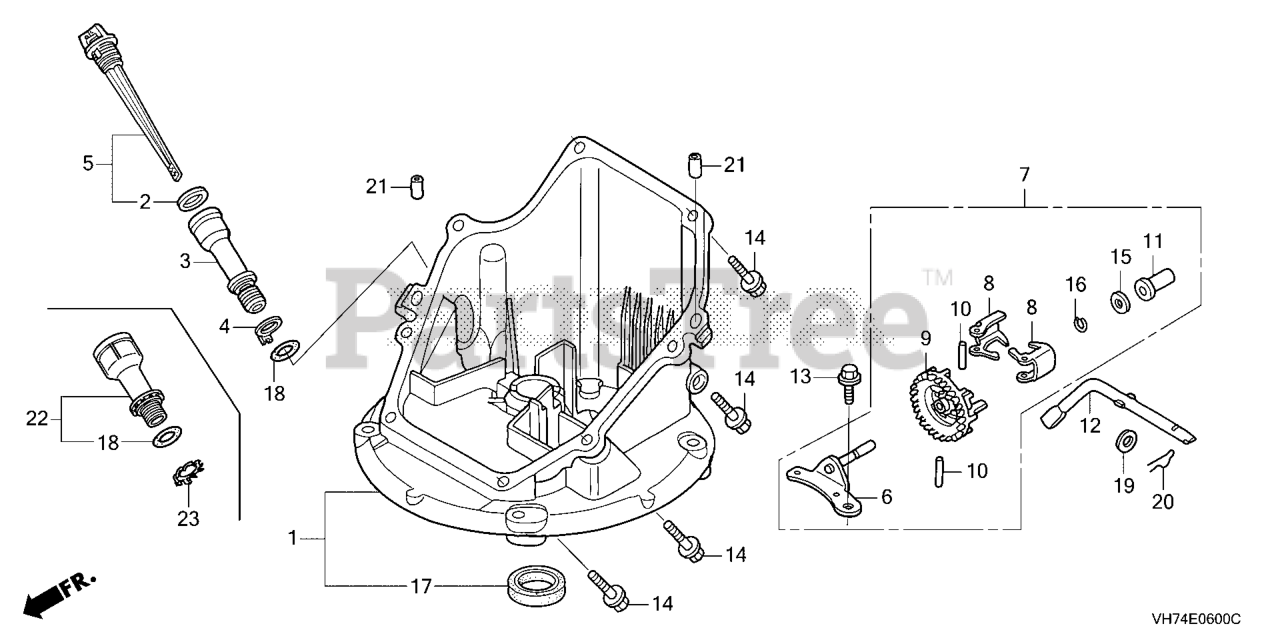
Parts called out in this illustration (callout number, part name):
1	PAN ASSY., OIL
2	GASKET, OIL FILLER CAP Use up to Engine SN 1257294.
3	EXTENSION, OIL FILLER
4	WASHER, EXTENSION LOCK
5	GAUGE ASSY., OIL LEVEL
6	SHAFT, GOVERNOR HOLDER
7	GOVERNOR ASSY.
8	WEIGHT, GOVERNOR
9	HOLDER, GOVERNOR WEIGHT
10	PIN, GOVERNOR WEIGHT
11	SLIDER, GOVERNOR
12	SHAFT, GOVERNOR ARM
13	BOLT, FLANGE (6X14)
14	BOLT, FLANGE (6X25) Use up to Engine SN 2056819.
15	WASHER, THRUST (6MM)
16	CLIP, GOVERNOR HOLDER
17	OIL SEAL (28X41.25X6)
18	O-RING (14.8X2.4) (ARAI)
19	WASHER, PLAIN (6MM)
20	PIN, LOCK (8MM)
21	PIN, DOWEL (8X20)
22	EXTENSION, OIL FILLER
23	WASHER, EXTENSION LOCK
